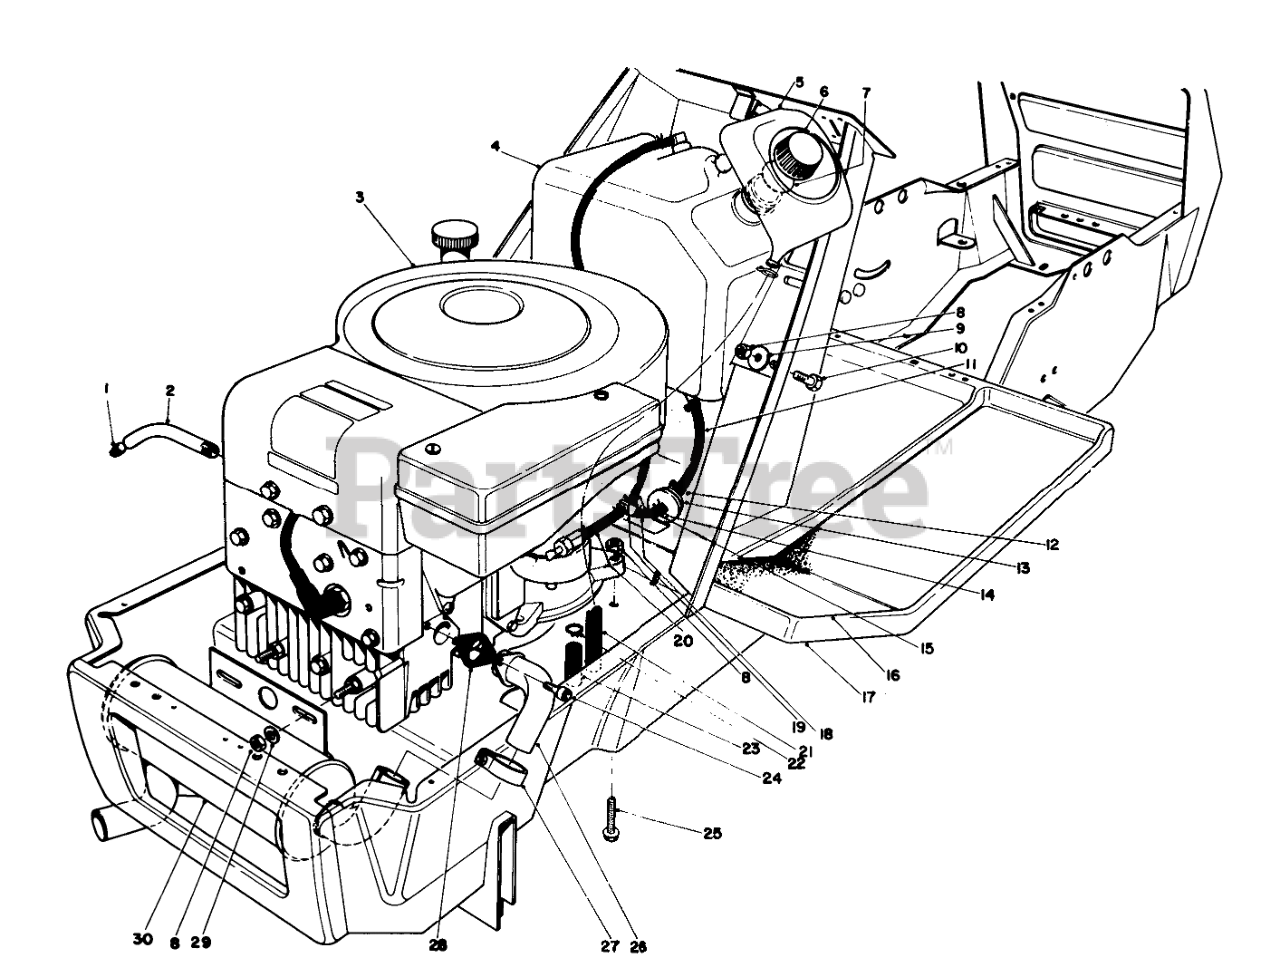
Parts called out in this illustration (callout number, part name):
1	PLUG-PIPE, SQH
2	OIL DRAIN TUBE
3	Engine
4	Gas Tank (Incl. Ref. #5)
5	Funnel Overflow
6	Gas Cap Assembly (Incl. Ref. #7)
7	Gasket Gas Cap
8	NUT-LOCK, CONE
9	WASHER
10	SCREW-HH
11	Gas Hose
12	CLAMP-HOSE
13	Nut
14	Clamp
15	Hose Gas Return
16	LH FOOT TREAD
17	Frame
18	Hose Gas
19	Fitting-Barbed Y
20	Hose Gas
21	Hose Funnel
22	HOSE CLAMP
23	CARB DRAIN HOSE
24	SCREW-HSH
25	SCREW-HH
26	Exhaust Pipe
27	MUFFLER CLAMP
28	Gasket Exhaust
29	WASHER-PLAIN
30	EXHAUST MUFFLER 10 HP
